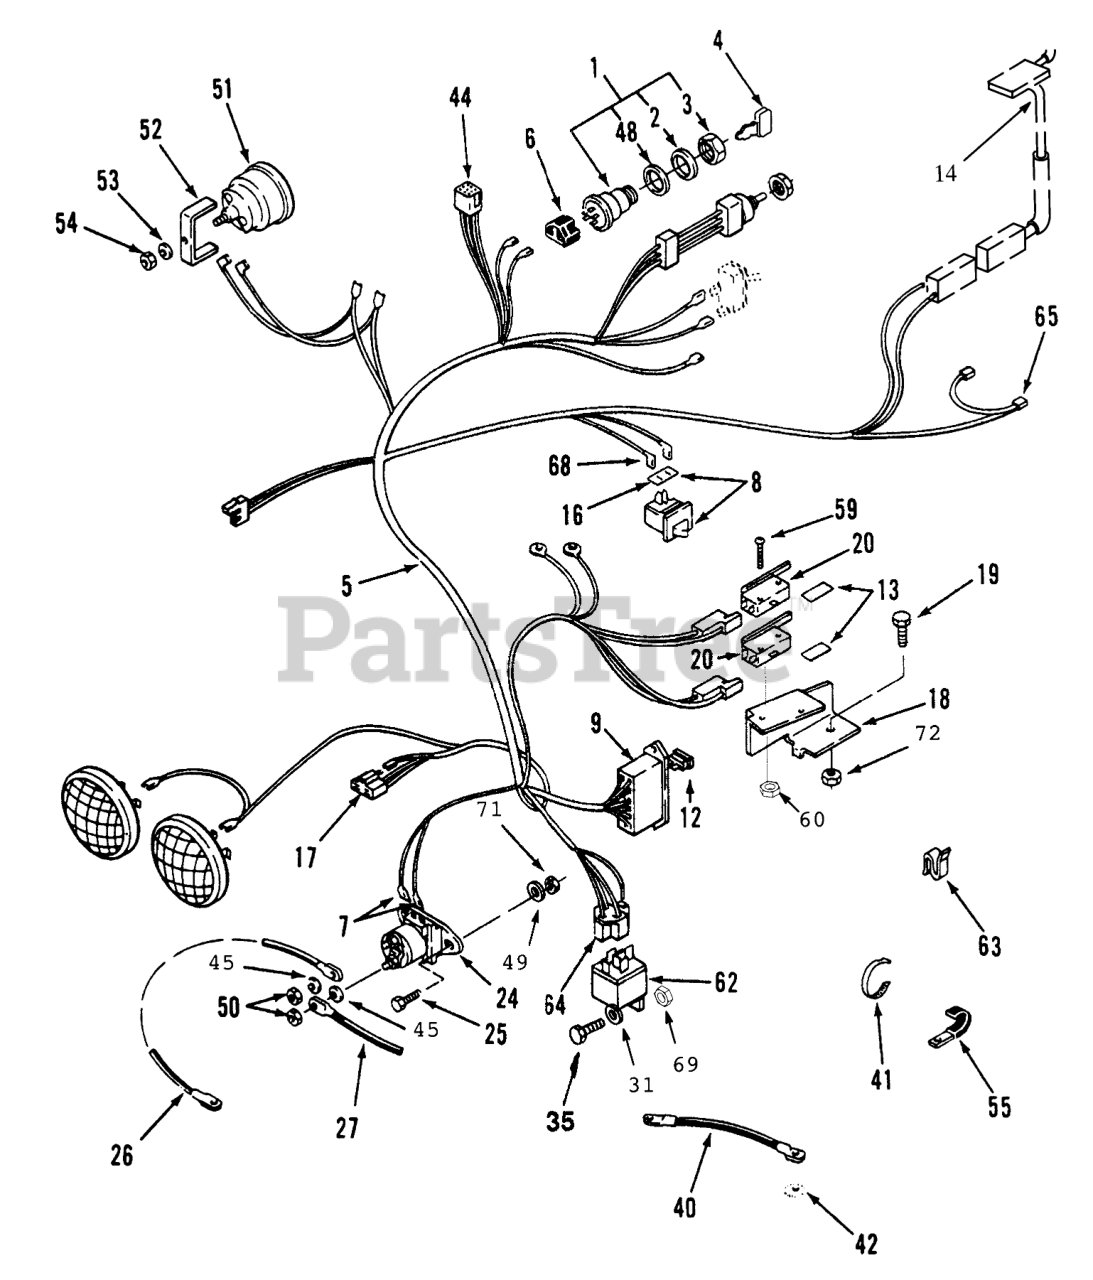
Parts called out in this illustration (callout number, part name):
1	KEY SWITCH ASM
2	LOCKWASHER
4	KEY-IGNITION
5	Harness Assy-Wiring (Incl Ref.#6-9,44,& 64-68 )
6	CONNECTOR BODY ELECT
7	TERMINAL 10
8	Switch-Clutch Interlock (Incl. Ref .#16)
9	FUSE-HOLDER 4 WAY
12	FUSE-BLADE, 15 AMP
13	BARRIER - SWITCH
14	SWITCH-SEAT
16	SHIELD-DIRT SPST
17	5-CONTACT CONN BODY
18	BRACKET-SWITCH
19	Bolt
20	SWITCH
24	Solenoid
25	Screw
26	ASSY WIRE
27	CABLE-BLACK
31	WASHER-FLAT
40	WIRE GROUND
41	TIE-CABLE
42	WASHER-LOCK, INTERNAL
44	Terminal
45	WASHER-LOCK
48	Washer
49	WASHER-LOCK/EXT
50	NUT-JAM
51	Meter-Hour (Incl. Ref.# 52-54)
52	CLAMP-HOUR METER
53	Washer-Lock
54	NUT-HEX
55	CLIP
59	Screw
60	NUT HEX 4-40 ELAST
62	RELAY
63	CLIP-CABLE
64	TERMINAL 10
65	Sur-Plug
68	Terminal
69	Nut
71	NUT-HEX
72	NUT-LOCK, NI
